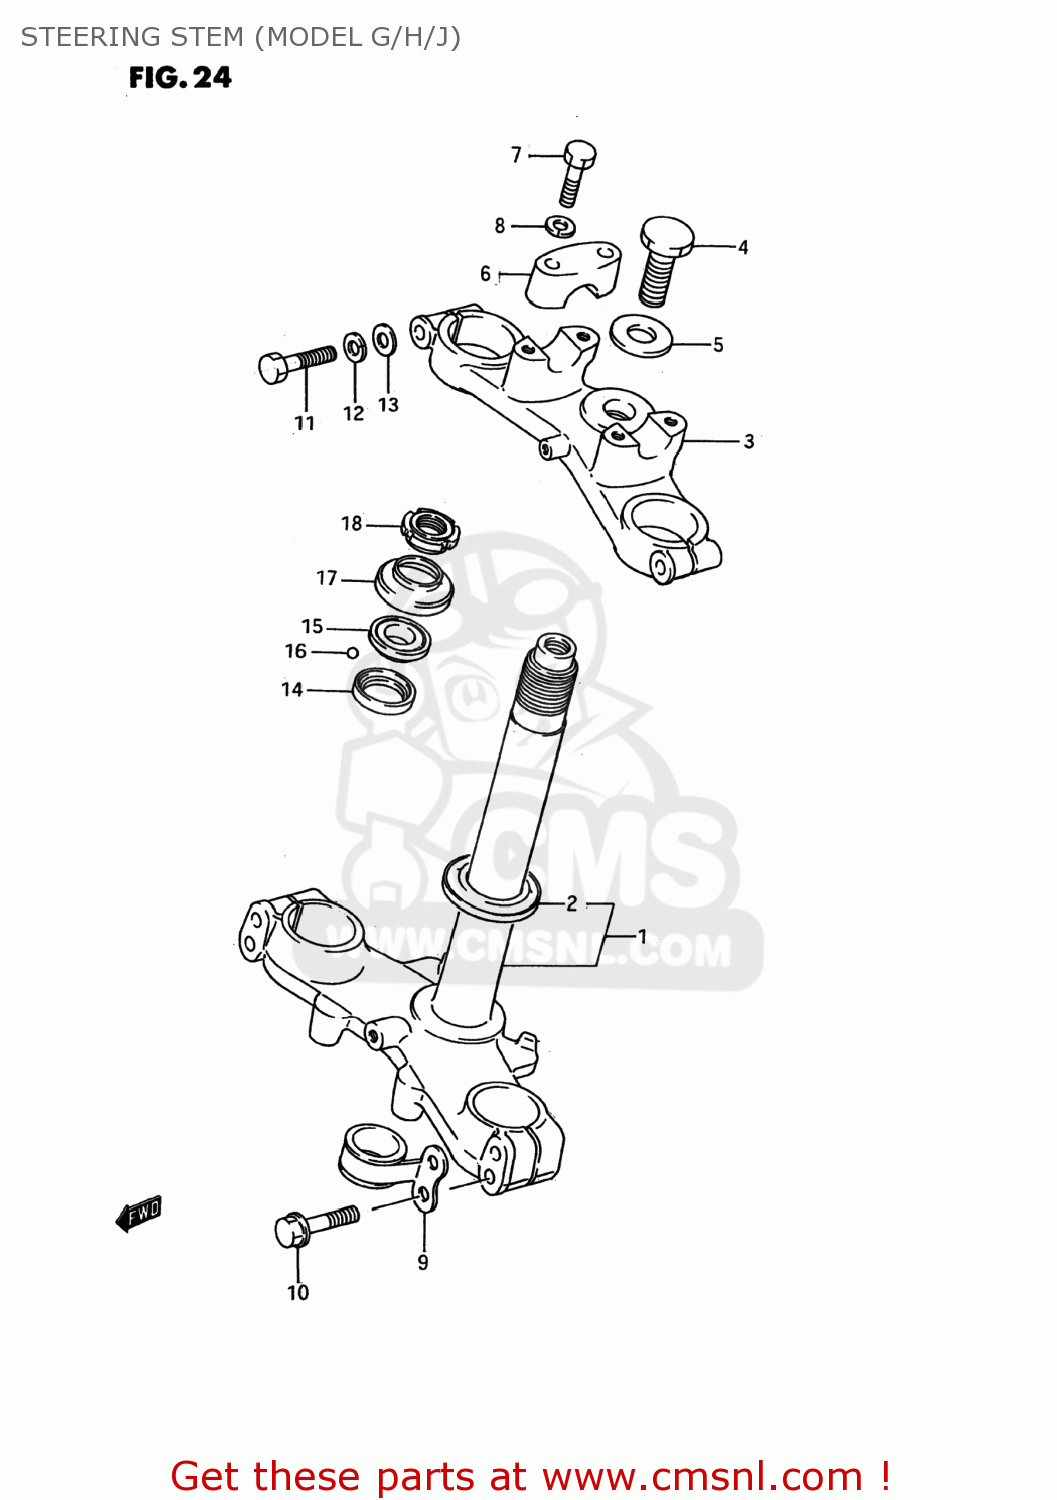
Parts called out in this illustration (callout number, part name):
1	STEM,STEERING
2	RACE
3	HEAD,STEERING STEM
4	BOLT,STEERING STEM HEAD
5	WASHER
6	HOLDER,HANDLEBAR
7	BOLT
8	LOCK WASHER
9	CLIP
10	BOLT 8X40
11	BOLT 8X40
12	LOCK WASHER
13	WASHER
14	RACE,STEERING INNER (SUJ)
15	RACE,STEERING,OUTER,UPPER
16	BALL
17	DUST SEAL,STEERING,UPPER
18	NUT,STEERING STEM(25X44X10)
